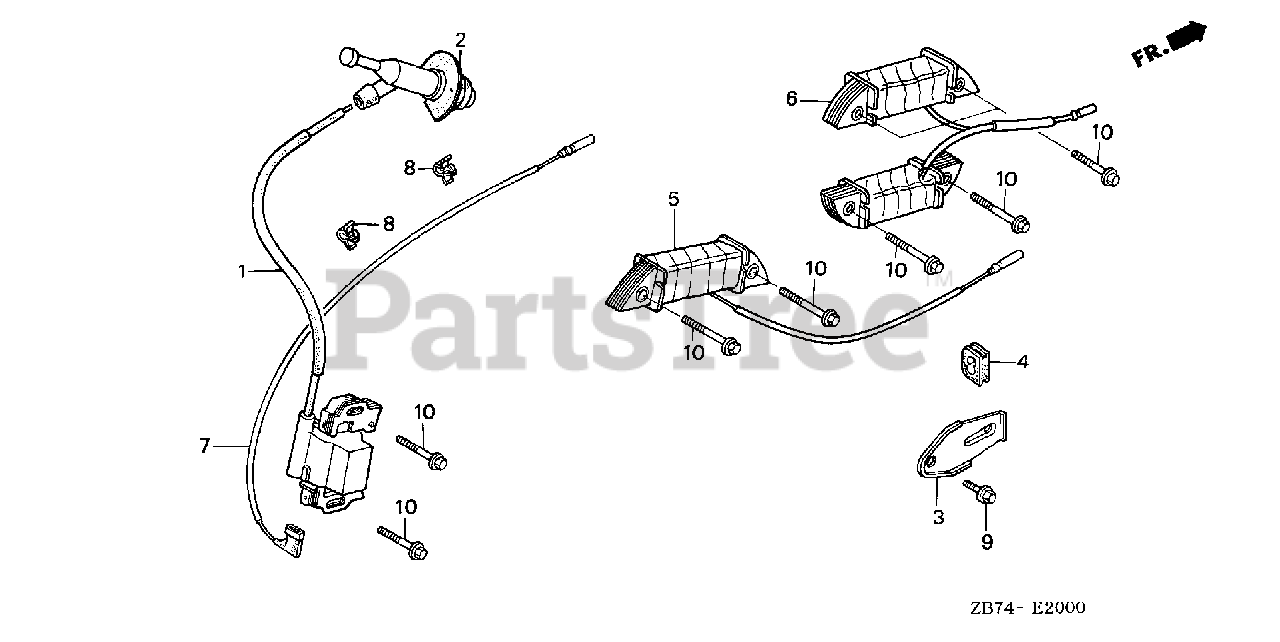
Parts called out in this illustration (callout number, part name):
1	COIL ASSY., IGNITION
2	CAP ASSY., NOISE SUPPRESSOR (NICHIWA Y-EZ RTFM256)
3	CLAMP, WIRE
4	GROMMET, WIRE
5	COIL ASSY., LAMP (12V/25W)
6	COIL ASSY., CHARGE
7	WIRE, STOP SWITCH (430MM)
9	BOLT, FLANGE (6X12) (CT200)
10	BOLT, FLANGE (6X28) (CT200)
